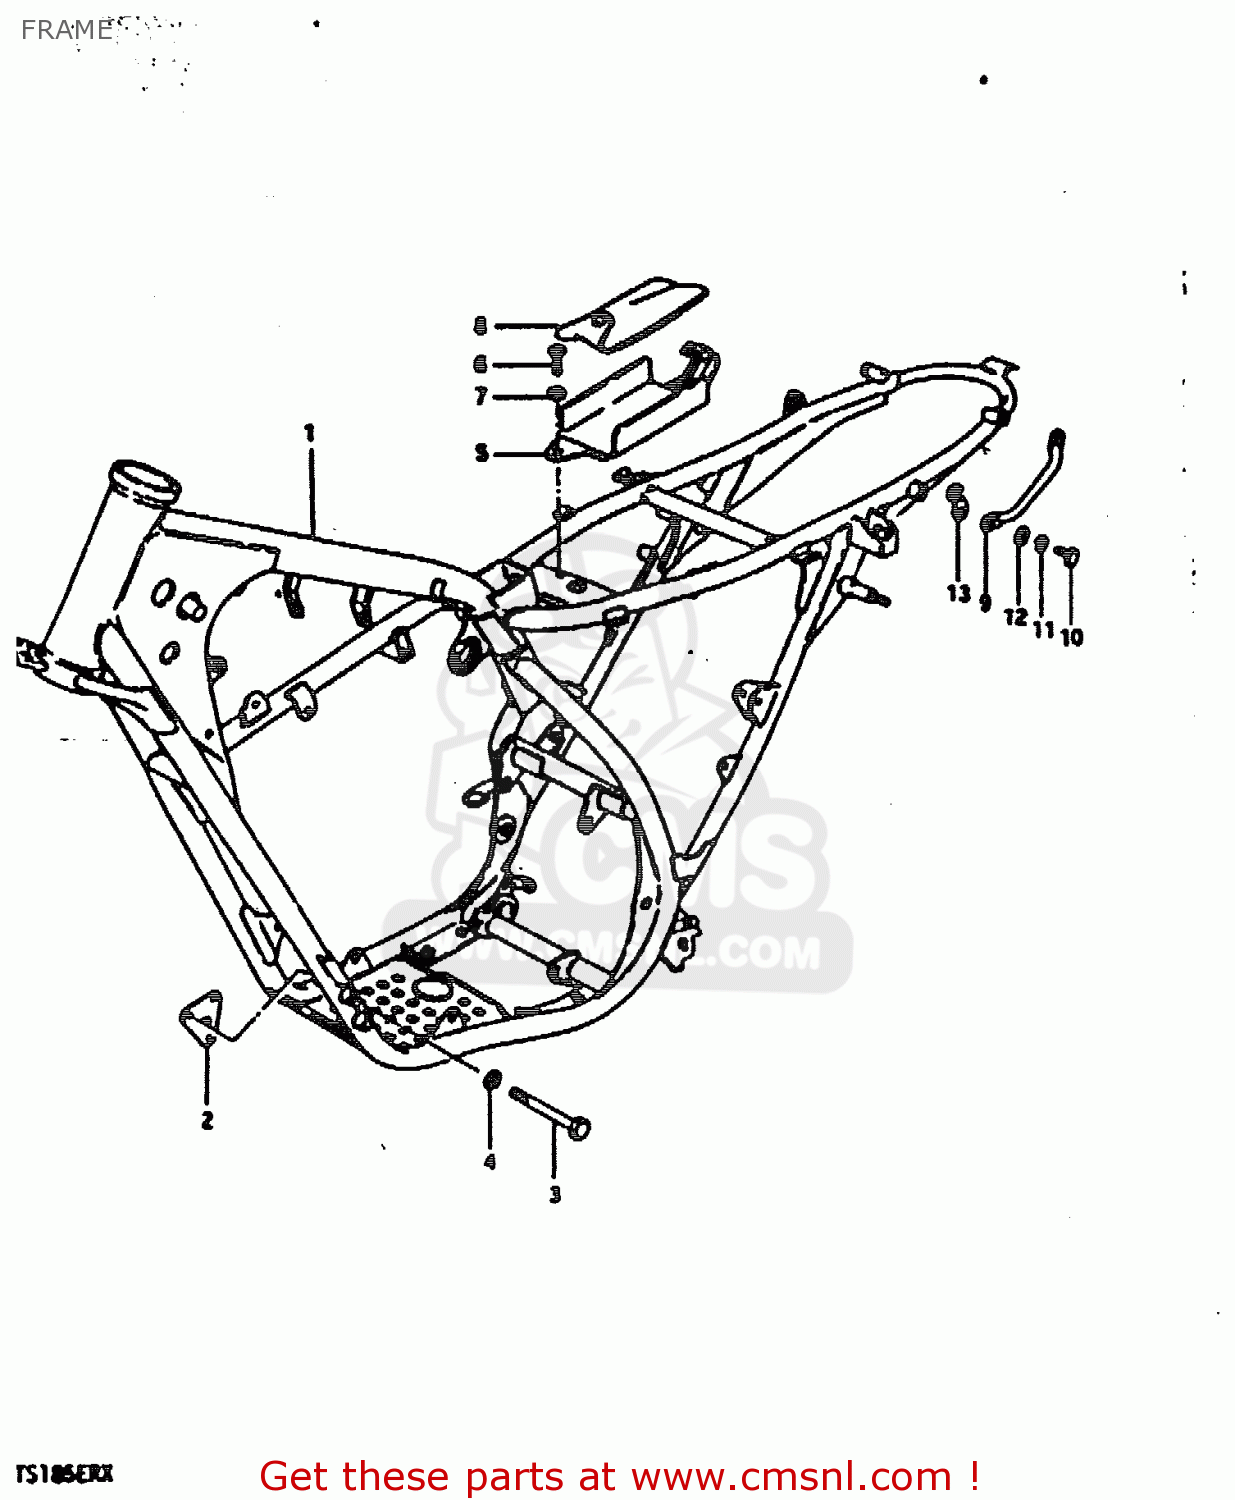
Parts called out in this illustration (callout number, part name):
1	FRAME
2	PLATE,ENG MTG,L
3	BOLT 8X55
4	WASHER
5	HOLDER,TOOL
6	SCREW
7	WASHER
8	TOOL SET
9	GRIP,FRAME HANDLE
10	BOLT
11	LOCK WASHER
12	WASHER
13	HOOK,HELMET HOLDER
